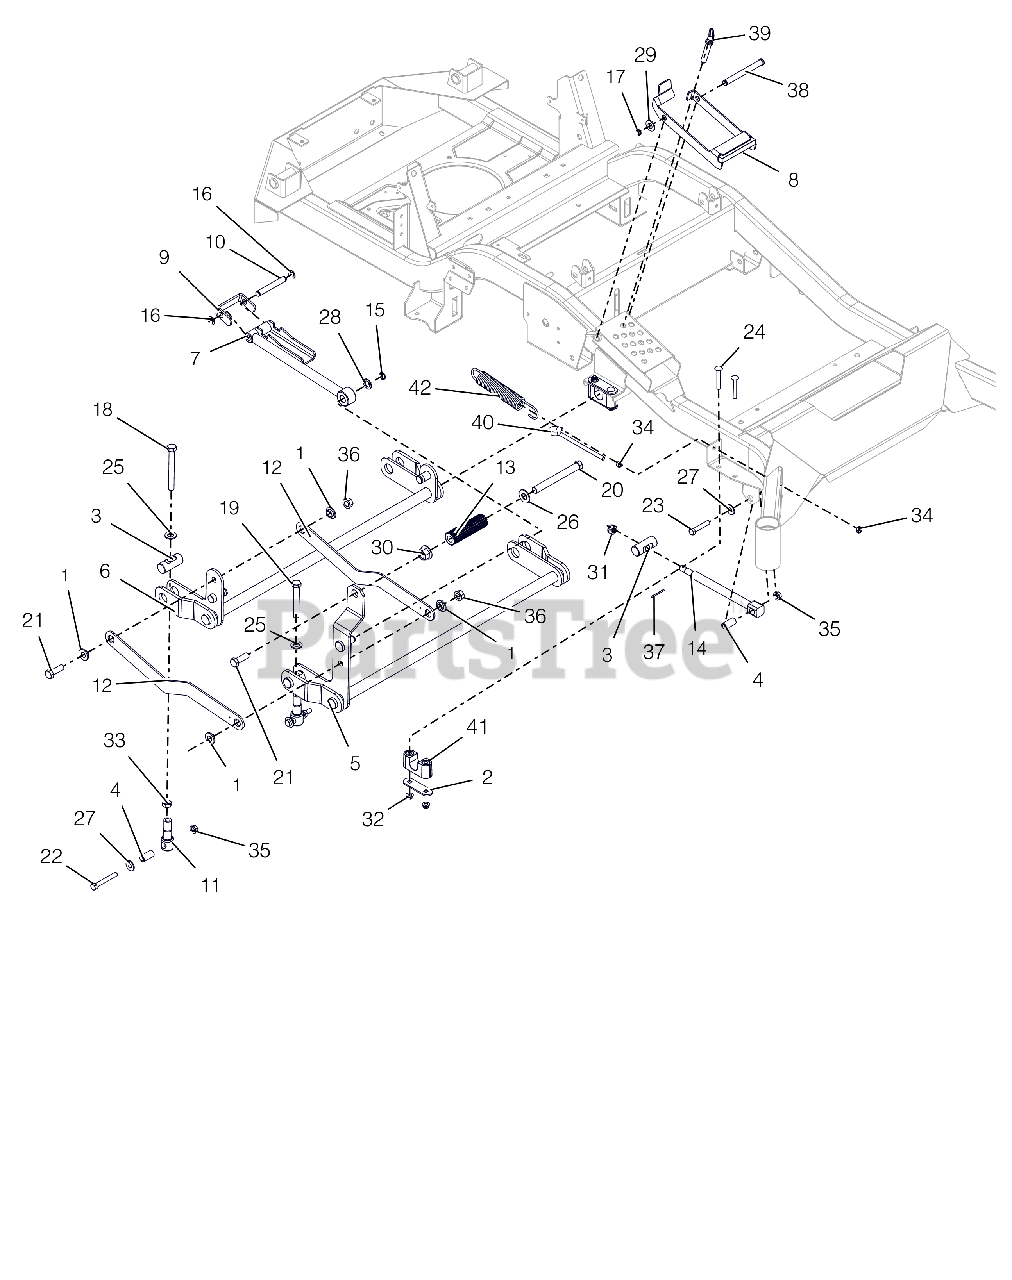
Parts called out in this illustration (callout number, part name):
1	BSHG-FLG .515X.750X.395X1.120
2	PLATE, BEARING SUPPORT
3	PIN, DECK LIFT
4	SPACER, DECK LEVELING
5	WLDMT, FRONT DECK LIFT PIVOT
6	WLDMT, REAR DECK LIFT PIVOT
7	WLDMT, HOC ARM
8	BRKT, HOC TRANSFER LOCK
9	BRKT, HOC LINE
10	ROD, HOC PIVOT
11	LINK, DECK LIFT FORMED
12	LINK, DECK LIFT
13	ROD, FOOT PEDAL (BLACK)
14	DRAG,LINK-HD
15	RG-RTNG-EXT .625X.050
16	RG-RTNG-EXT .500X.042 (E)
17	RG-RTNG-EXT .500X.050 (SNAP)
18	@BLT-HEX .5-13-4.5GR8 FULL THD
19	BLT-HEX .50-13X3.50 GR5 FTH
20	BLT, HEX .62-11X5.50 G5 FBP
21	@BLT-HEX .50-13X1.50 GR5 YWZC
22	BLT-HEX .38-16X2.75 GR8 YWZC
23	@BLT-HEX .38-16X2.00 GR5 YWZC
24	BLT-RDHDSQSHNK .31-18X2.25 YWZ
25	FLATWASHER 1/2 SAE HARD 15906
26	WSHRFLT 5/8SAE CARBHARD FBP
27	@WSHR-FL-STL.438X1.00X.083 YWZ
28	WSHR-FL-STL .630X1.005X.062 YZ
29	@WSHR-FL-STL.531X1.06X.095YWZC
30	NUT,FLG-TOP LK .625-11 FBP
31	NUT-SL .50-13
32	@NUT-LK-CTR-FLG .31-18 YZ GR F
33	NUT-JAM .50-13 YWZC
34	NUT-HEX-JAM .375-16 YWZC
35	@NUT-LK-TOP-FLG .38-16 YWZC
36	@NUT-LK-TOP-FLG .50-13 YWZC
37	@PIN-CTR .12X1.25 EXTPRSQCT YZ
38	PIN-CLEV .50X4.75X4.55
39	PIN, .50 X 2.20 USABLE LG BALL
40	BOLT,.38-16 X 5.25-.62 DIA EYE
41	ASM-BUSHING, DECK LIFT
42	SG-TENS .162X1.25X8.25 WLD 25
